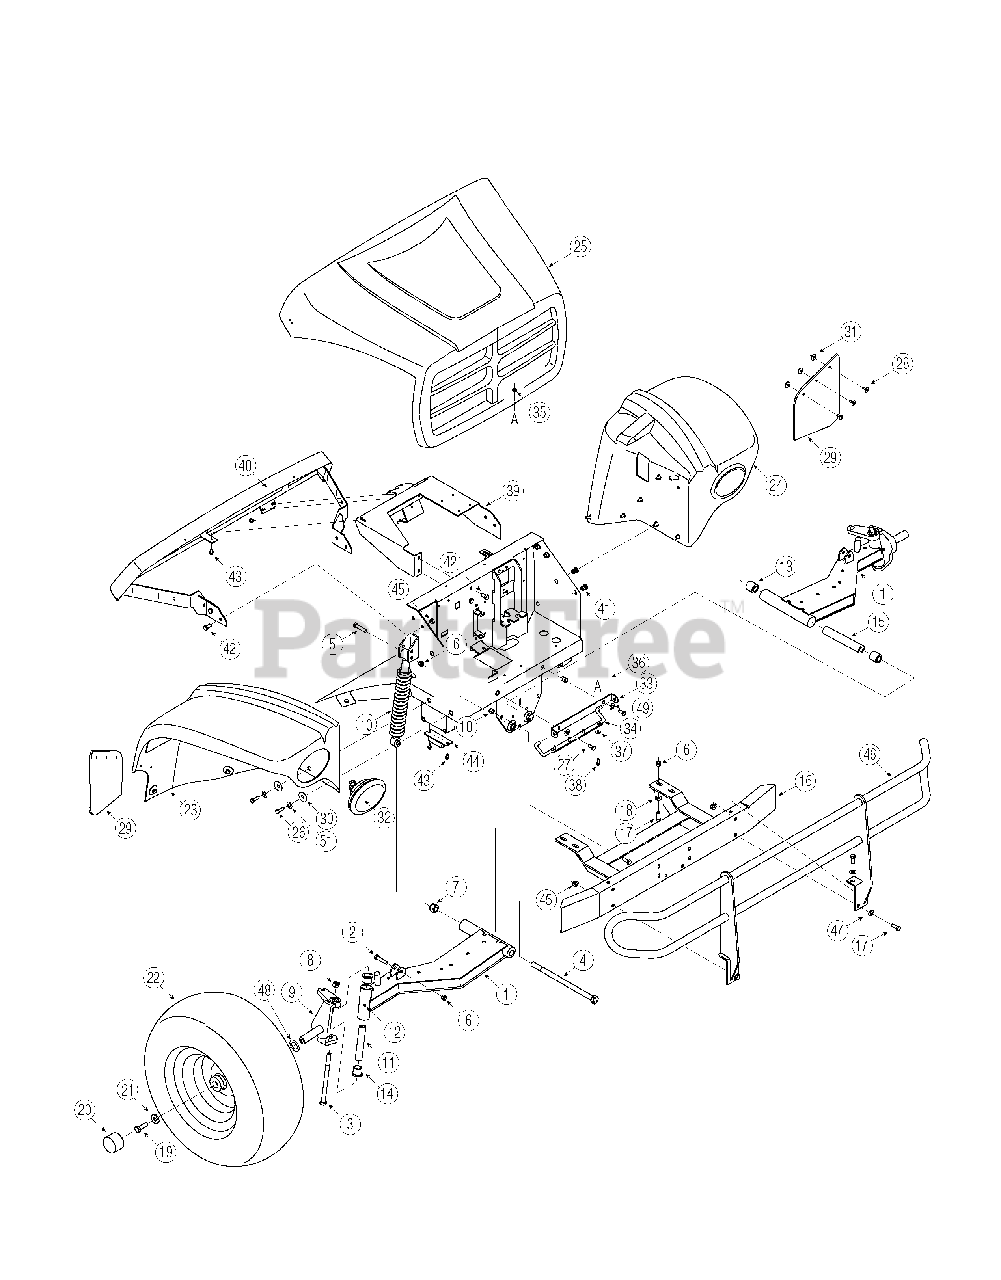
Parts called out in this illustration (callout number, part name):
1	Axle Assembly, Right-front (Incl. Ref 12 - 15)
2	Hex Screw, 3/8-16 x 1.75
3	Hex Screw, 1/2-13 x 7.0, Gr5
4	Hex Screw, 5/8-11 x 11.13, Gr5
5	Hex Screw, 3/8-16 x 2.25
6	Nut, Hex Lock, Nylon, 3/8-16, Gr5
7	Nut, Hex Lock, Nylon, 5/8-11, Gr5
8	Nut, Hex Lock, 1/2-13
10	Shock Absorber, 2.9 Stroke
11	Tube, .875 x .50 x 4.75
12	Grease Fitting
13	Bearing, .63 ID x 1.19 OD
14	Bushing, Steering
15	Spacer, .645 ID x 1.063 OD
18	Flat Washer,.406 x.875 x.059
19	Hex Screw, 1/2-13 x 1.25, Gr5
21	Flat Washer,.531 x 1.25 x.181
22	Wheel Ass’y, 22 x 11 x 10, RH, All Terr.
22	Wheel Ass’y, 22 x 11 x 10, LH, All Terr.
23	Panel, Right Fender, Camo
24	Panel, Left Fender, Camo
25	Panel, Hood, ABS Camo Dark
26	Hex Screw 5/16-18 x 1.00 Gr 5
27	Hex Screw, 5/16-18 x.75
28	Pop Rivet
30	Lock Washer 5/16
31	Flat Washer, .194 x .62 x .063
32	Head lamp Assembly
35	Nut, Hex Lock, 1/4-20
36	Cotter Pin, Internal, 1.42
37	Washer, Flat,.271 x.63 x.065
38	Hex Screw, 1/4-20 x.75
41	Insert Nut, 5/16-18
42	Hex Screw, 3/8-16 x.75
43	Screw, Self-tapping, 1/4-20 x.5
44	Suspension Bumper
45	Flange Lock Nut, 3/8-16
46	Brush Guard
47	Washer, Flat, 406 x .810 x .051
48	Washer, Flat, 030 x .625 x .090
49	Flat Washer .344 x .688 x .065
